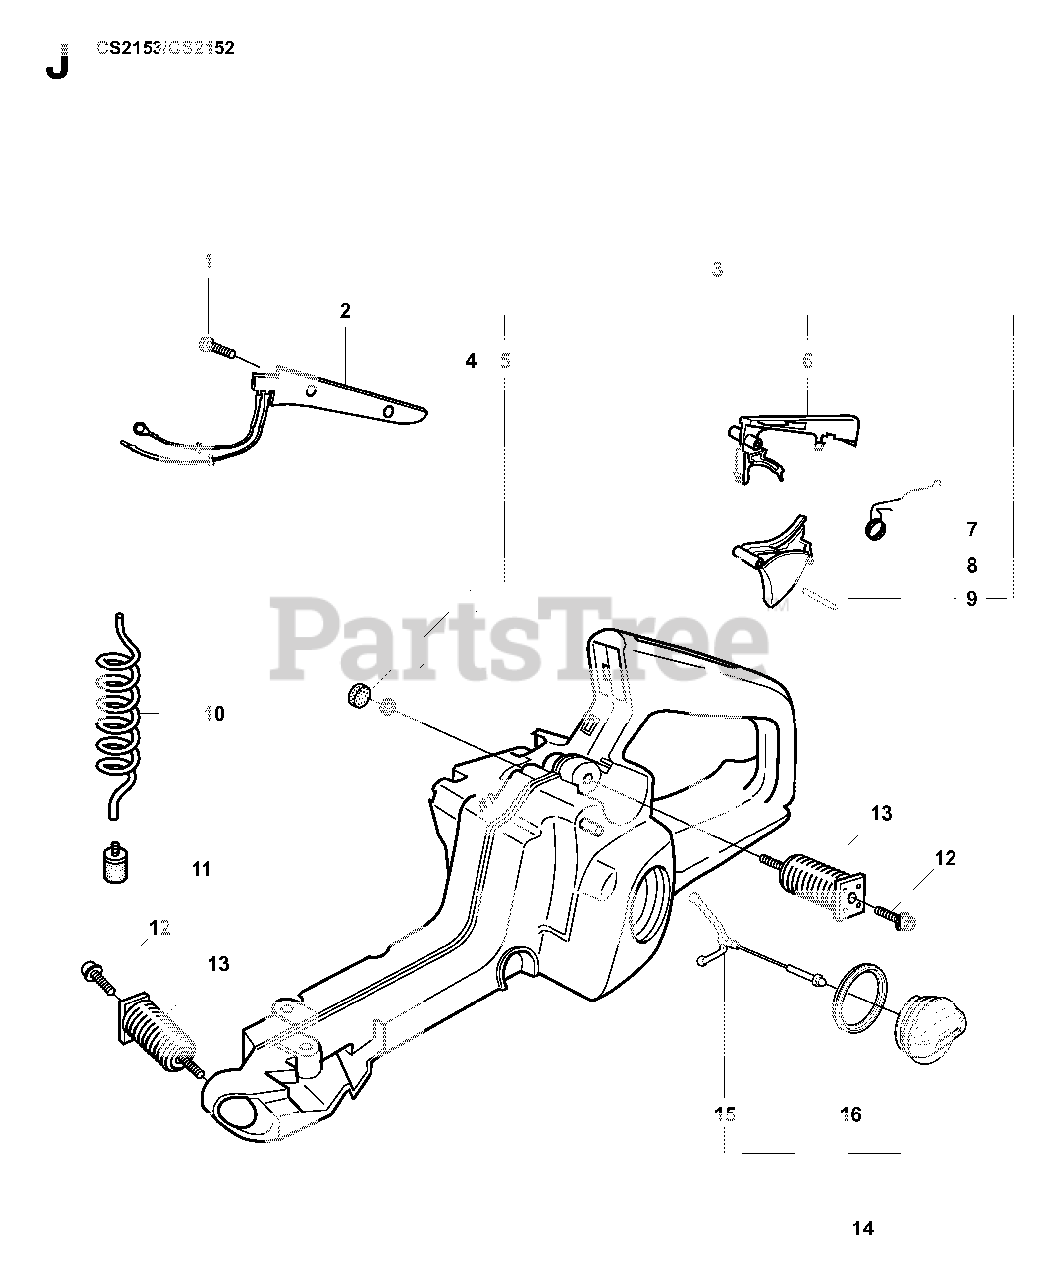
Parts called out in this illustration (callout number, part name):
2	HANDLE CIRCUIT
3	TANK UNIT
4	FILTER PLUG
5	VALVE PLUG
6	THROTTLE LOCK
8	THROTTLE TRIGGER
10	FUEL HOSE
11	FUEL FILTER
13	VIBRATION ABSORBER
14	TANK CAP
16	SEALING
